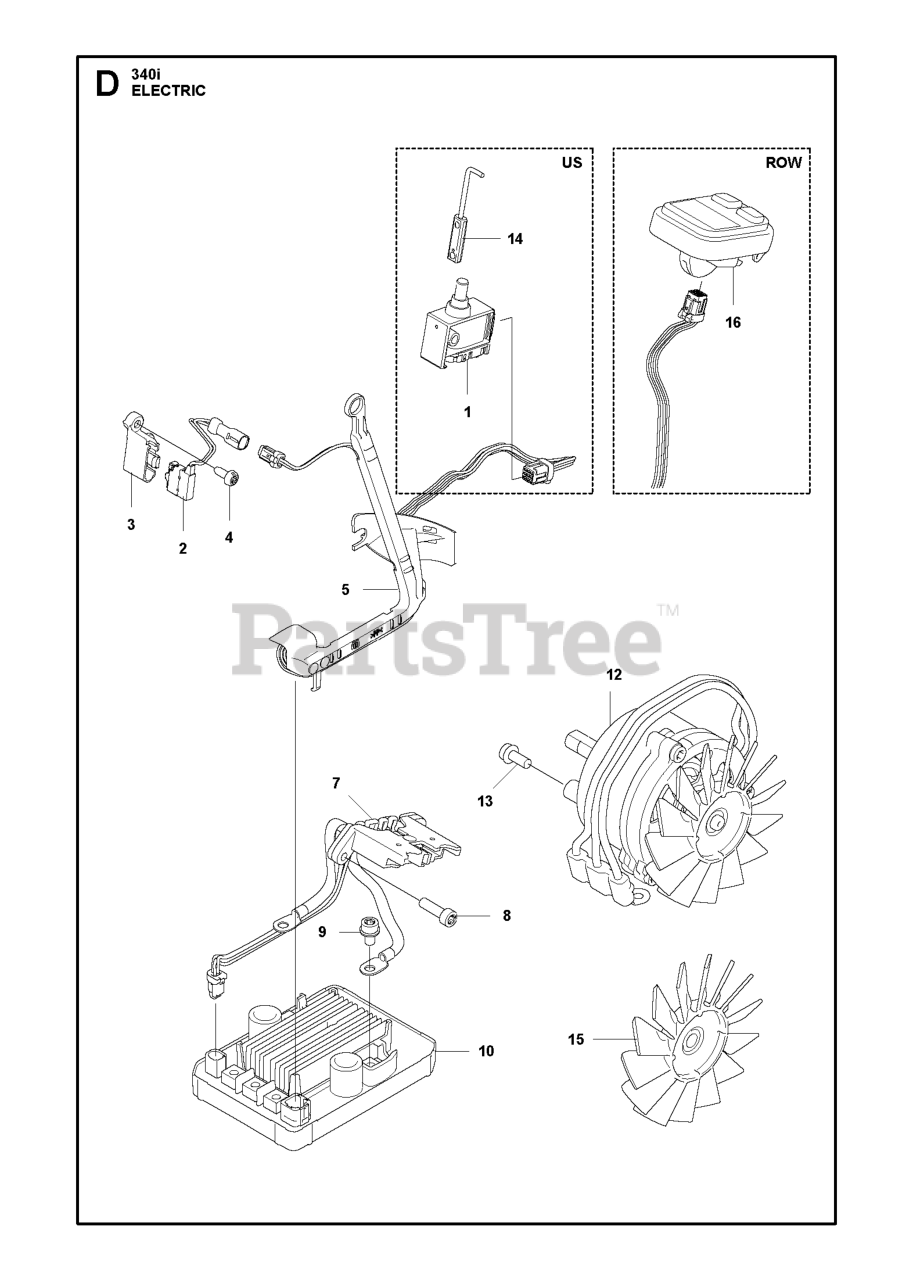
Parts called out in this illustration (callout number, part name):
1	TRIGGER SWITCH IPX4
5	Wiring Harness
7	Wiring Harness
8	SCREW ITXSCT PW4.2X18 10.9 ZN
9	SCREW ITXSCFM M5X8 T27 10.9 Z
10	CONTROL UNIT
12	Motor
13	SCREW
14	THROTTLE ROD ASSY
16	Control Panels
